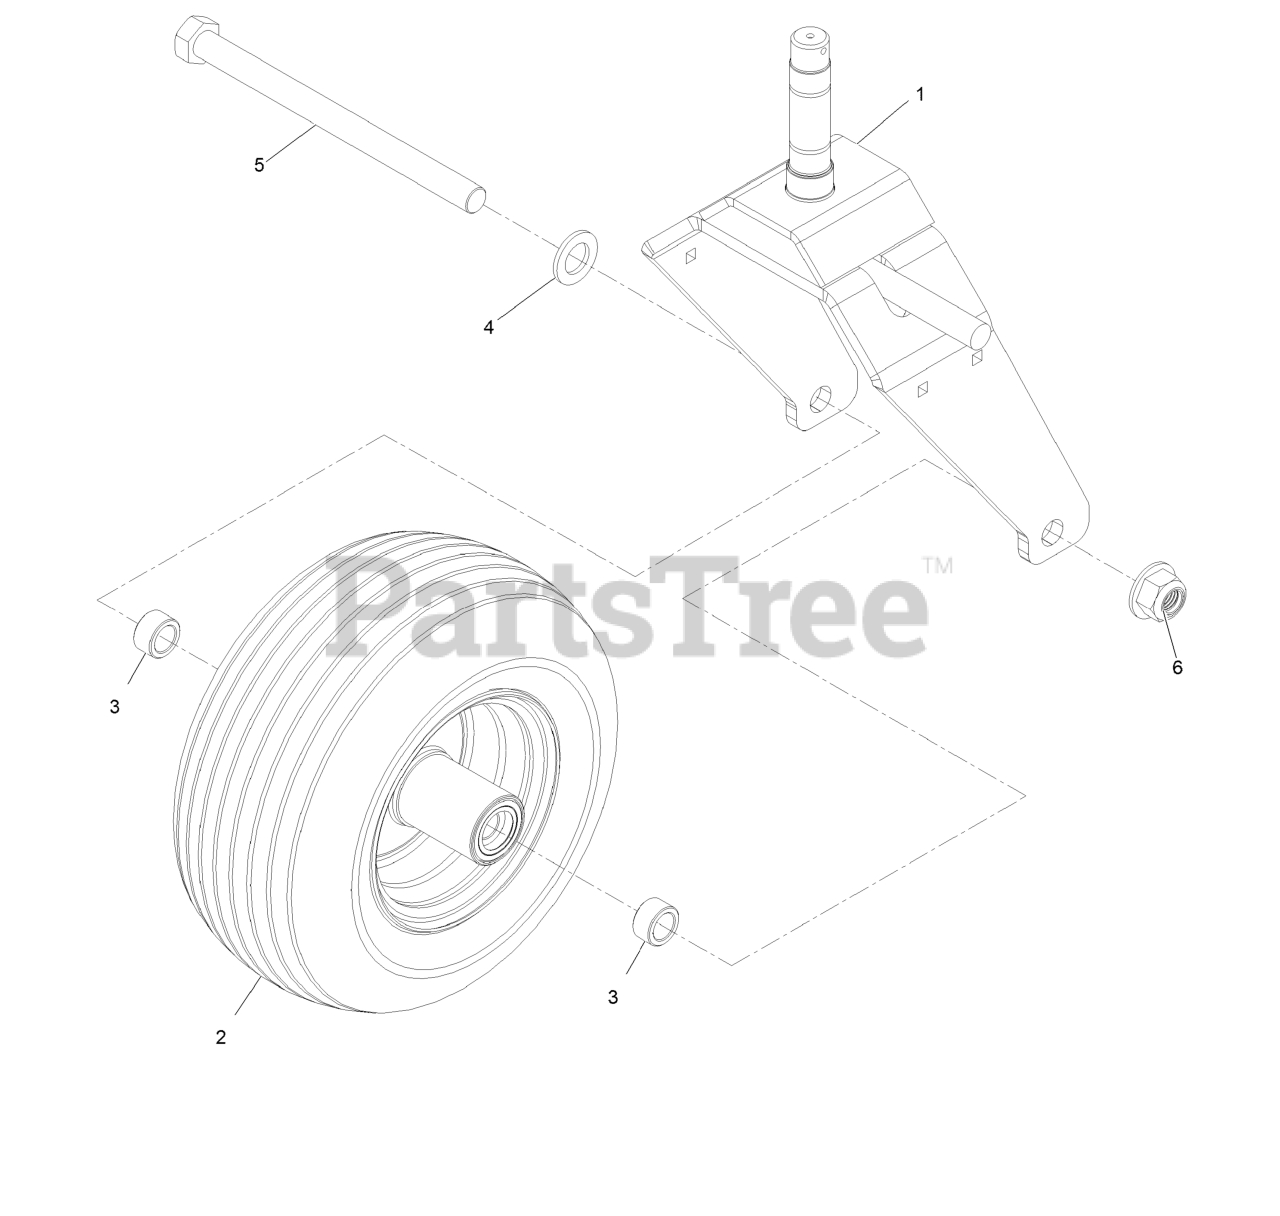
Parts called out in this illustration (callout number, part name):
1	Fork-Caster, RH [red]
2	TIRE, FRONT, ZPLUG,J36,36
3	SPACER-AXLE
5	SCREW-HH
